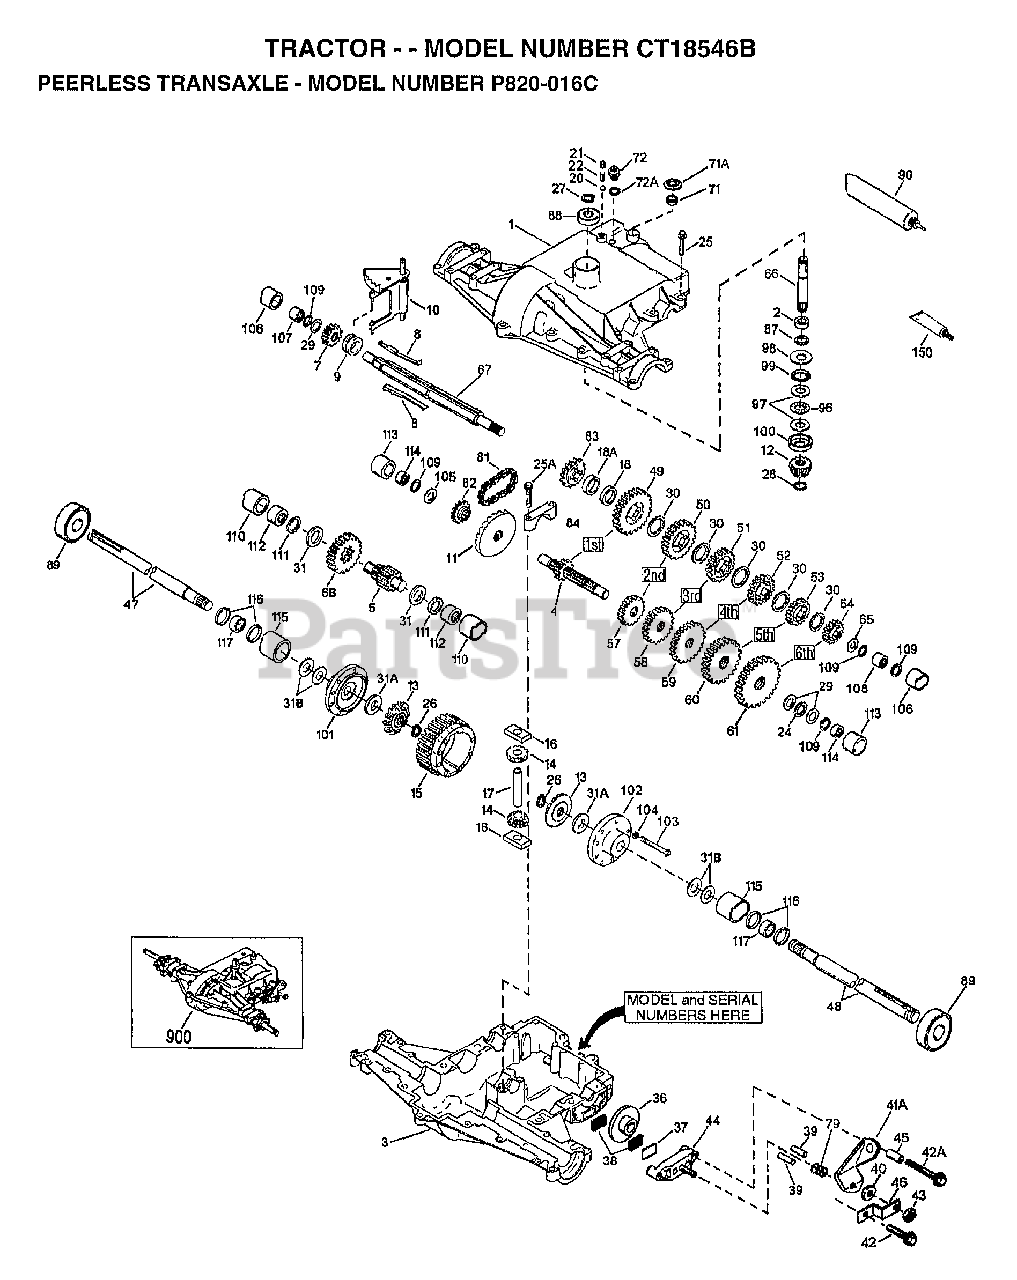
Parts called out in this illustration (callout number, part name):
1	COVER TRANSAXLE
2	BEARING NEEDLE
3	CASE TRANSAXLE
4	SHAFT COUNTER
5	SHAFT, OUTPUT, 9T
6	GEAR, OUTPUT, 35T
7	GEAR, SPUR, 15T
9	COLLAR SHIFT
10	ROD AND FORK ASSY SHIFT
11	GEAR BEVEL, 33T
12	BEVEL PINION, 13T
14	PINION, 10T
15	GEAR, RING, 31T
16	BLOCK DRIVE
18	SPACER, .350/.340 THICK
18A	SPACER, .276/.268 THICK
20	BALL STEEL, 5/16" DIA.
21	SCREW, 3/8-16 X 3/8"
24	THRUST BEARING
25	SCREW HEX HD 5/16-18 X 1-1/4
25A	SCREW, 1/4-20 X 1-1/4
28	RETAINING RING
29	WASHER THRUST
30	WASHER THRUST
31	WASHER THRUST
31B	WASHER THRUST
37	PLATE BRAKE PAD
41	LEVER BRAKE
42	SCREW, 1/4-20 X 1-1/4
42A	SCREW, 1/4-20 X 2-1/4
43	LOCKNUT 5/16-24
44	HOLDER BRAKE PAD
46	BRKT BRAKE LEVER
47	AXLE, 12-5/16" LONG
48	AXLE, 16-3/16" LONG
49	GEAR, SPUR, 41T
50	GEAR, SPUR, 35T
51	GEAR, SPUR, 30T
52	GEAR, SPUR, 25T
53	GEAR, SPUR, 22T
54	GEAR, SPUR, 19T
57	GEAR, SPUR, 15T
58	GEAR, SPUR, 20T
59	GEAR, SPUR, 25T
60	GEAR, SPUR, 28T
61	GEAR, SPUR, 31T
66	SHAFT INPUT
67	SHAFT BRAKE
71	SEAL SQUARE CUT
72	THREADED PLUG 9/16-18
81	CHAIN, ROLLER
82	SPROCKET 9T
83	SPROCKET 18T (REV)
84	BEARING CAP
87	OIL SEAL 3/4
88	BEARING BALL
89	BEARING BALL
90	GREASE BENTONITE, 32 OZ.
96	BEARING THRUST
97	WASHER THRUST
100	WASHER CUPPED
101	CARRIER DIFF THREADED HOLES
102	CARRIER DIFF
103	SCREW, 1/4-20 X 2-1/4
104	WASHER LOCK 1/4
107	BEARING NEEDLE
108	BEARING NEEDLE
110	SLEEVE STEPPED
111	RING SQ CUT
112	BEARING NEEDLE CAPPED
113	SLEEVE STEPPED
114	BEARING NEEDLE CAPPED
115	SLEEVE STEPPED
116	RING SQ CUT
117	BEARING NEEDLE
150	GASKET ELIMINIATOR
900	TRANSAXLE, COMPLETE
